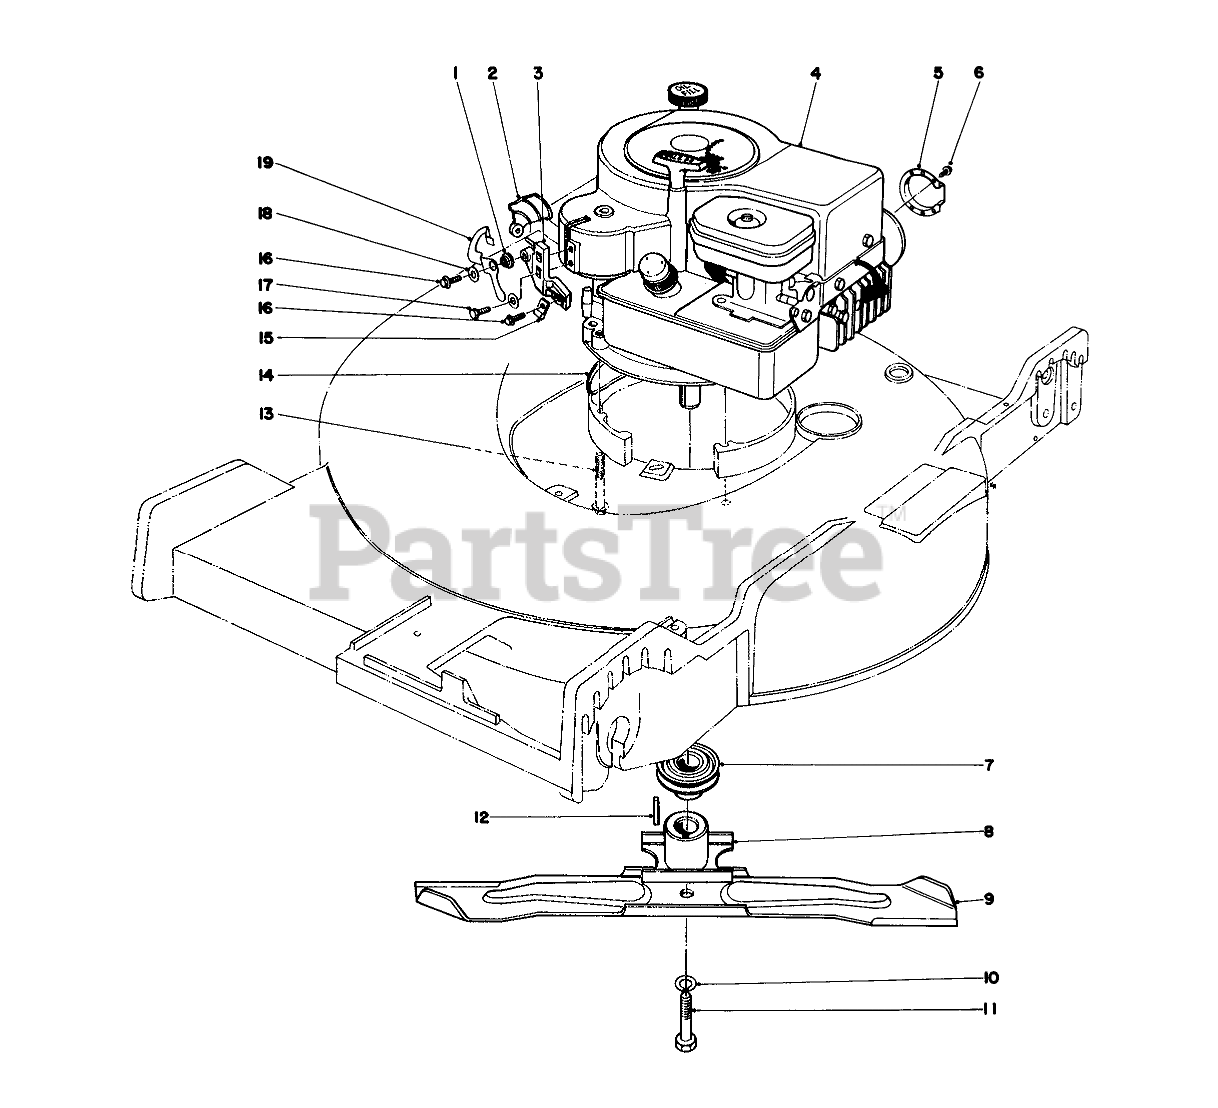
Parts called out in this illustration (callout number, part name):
1	BUSHING
2	INTERLOCK LEVER
3	CABLE & PIVOT BLOCK
4	Engine
5	Deflector
6	SCREW W/ENGINE
7	DRIVER PULLEY
8	BLADE RETAINER WA(BLACK)
9	Blade
10	WASHER-LOCK
11	BLADE SCREW
12	KEY-SQUARE
13	3/8-16 X 2-3/4 CAPSCR
14	HOUSING CAP
15	CLAMP
16	Screw
17	Screw
18	WASHER-FLAT
19	CAM INTERLOCK
